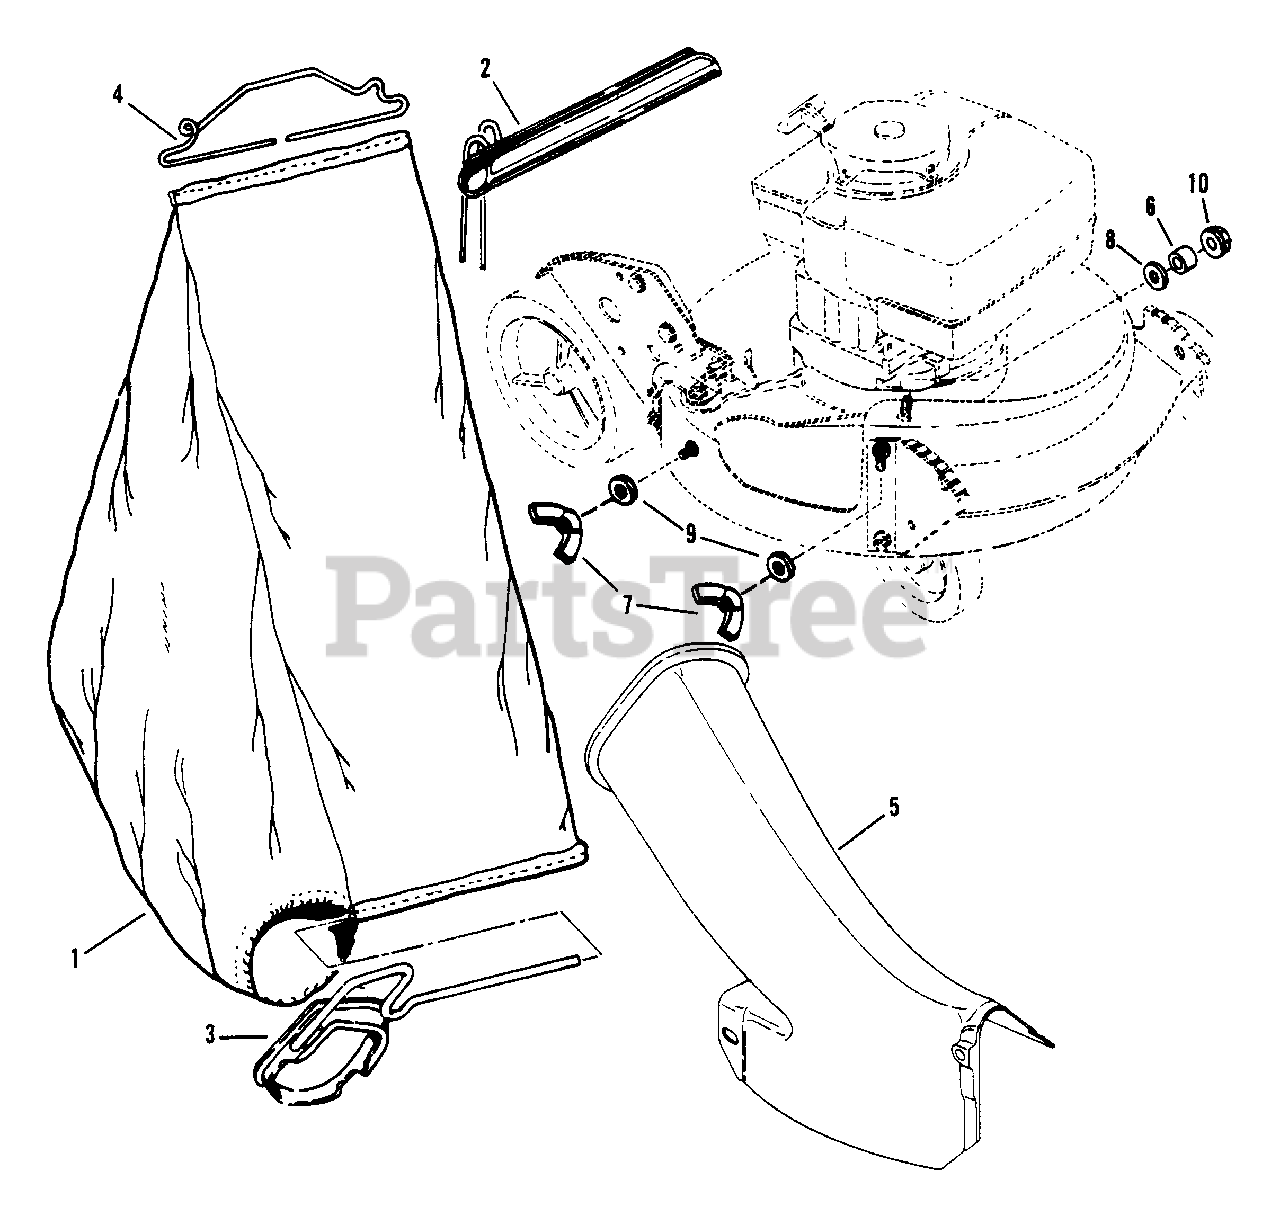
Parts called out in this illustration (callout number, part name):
1	BAG, Grass (Commercial)
2	ASSEMBLY, Slider
3	CONNECTOR, Grass Bag
4	WIRE, Bag Connector
5	ADAPTER, Bag
6	SPACER
7	NUT, 5/16-18 Wing (Nylon Patch)
8	RETAINER, 5/16 Bolt
9	WASHER, 5/16 Flat
10	NUT, 5/16-18 Hex Flange Lock
